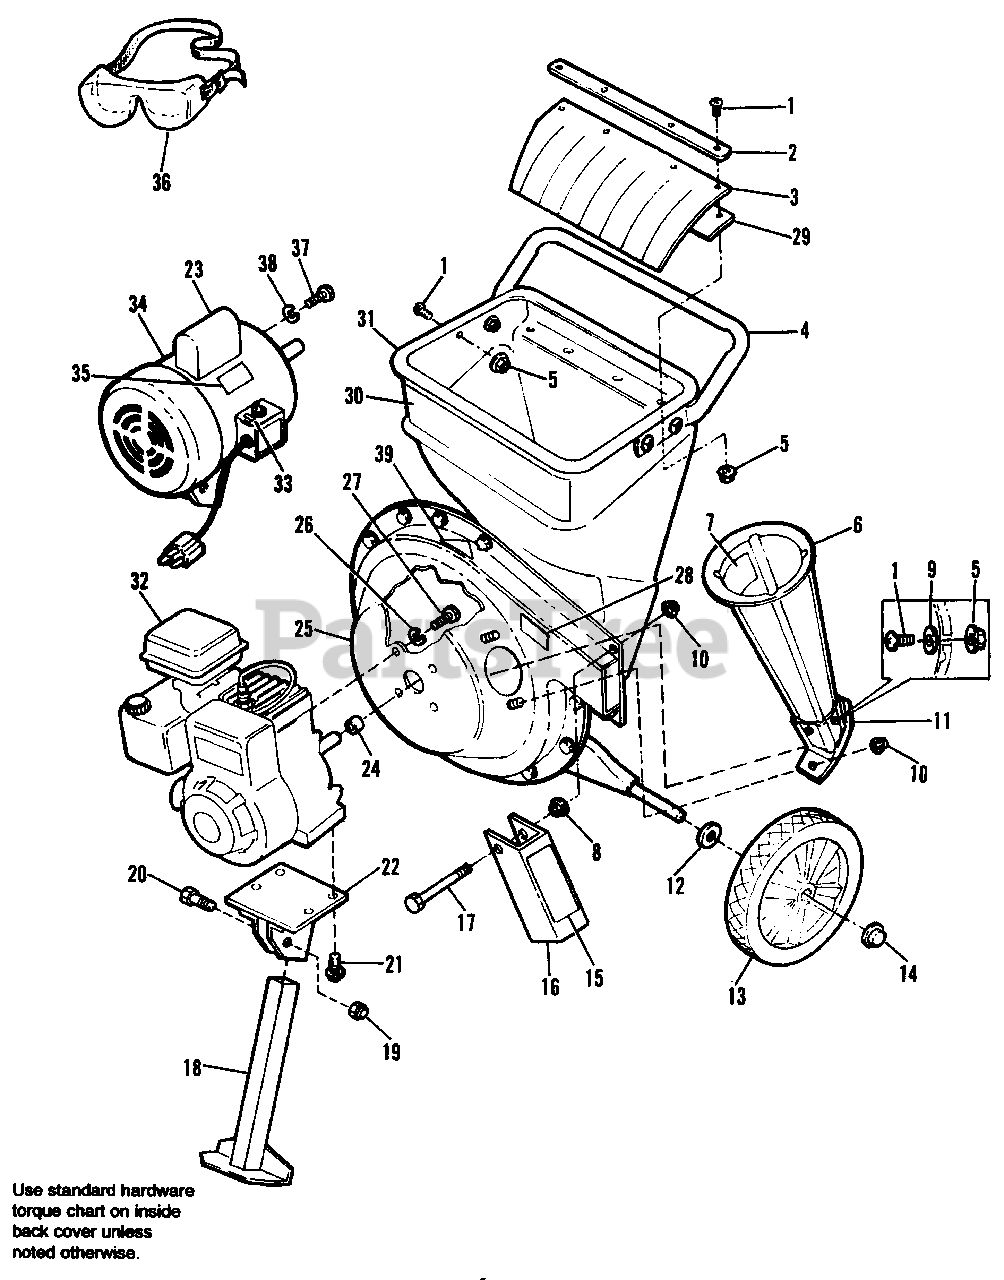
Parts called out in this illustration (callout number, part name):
1	SCREW, Hex, Button Hd., 1/4-20 x 3/4
2	RETAINING STRIP, Hopper Guard
3	GUARD, Hopper
4	HANDLE, Hopper
5	NUT, Flange, 2-Way, 1/4-20
6	CHIPPER CONE (Deep Orange)
6	CHIPPER CONE (Gold)
6	CHIPPER CONE (Red)
7	DECAL, Danger
8	NUT, Shoulder
9	WASHER, 1/4
10	NUT, Whiz, 5/16-18
11	CHIPPER CONE CASTING
12	WASHER, 1/2
13	WHEEL, 1-3/4 x 12
14	PUSH NUT, 1/2
15	DECAL, Danger (Narrow)
16	DISCHARGE DEFLECTOR
17	BOLT, Shoulder
18	LEG TUBE ASSY.(2C Only)
18	LEG TUBE ASSY. (3C Only)
19	NUT, ESNA, 5/16-18
20	CAPSCREW, Hex. Hd., 5/16-18 x 1-3/4
21	SCREW, Hex, Washer Hd., Taptite, 3/4-16 x 3/4 (3C Only)
22	LEG BRACKET ASSY.(3C Only)
23	MOTOR ASSY., 1-1/2 HP Electric (2C Only)
24	SPACER (3C Only)
25	CHIPPER HOUSING (2C Only)
25	CHIPPER HOUSING (3C Only)
26	LOCKWASHER, 5/16 (3C Only)
27	CAPSCREW, Hex Hd., 5/16-24 x 3/4 (3C Only)
28	I.D. PLATE
29	SUPPORT, Hopper Guard
30	DECAL, 2C Simplicity
30	DECAL, 3C Simplicity
30	DECAL, 2C Baker
30	DECAL, 3C Baker
31	SHREDDER HOPPER, (Deep Orange)
31	SHREDDER HOPPER, (Gold)
31	SHREDDER HOPPER, (Red)
32	ENGINE, Briggs & Stratton, 3 HP (3C Only)
33	DECAL, On Off (2C Only)
34	DECAL, Danger-Motor (2C Only)
35	DECAL, Caution-Motor (2C Only)
37	CAPSCREW, Hex Hd., 3/8-16 x 5/8 (2C Only)
38	LOCKWASHER, 3/8 (2C Only)
39	DECAL, OPEI
